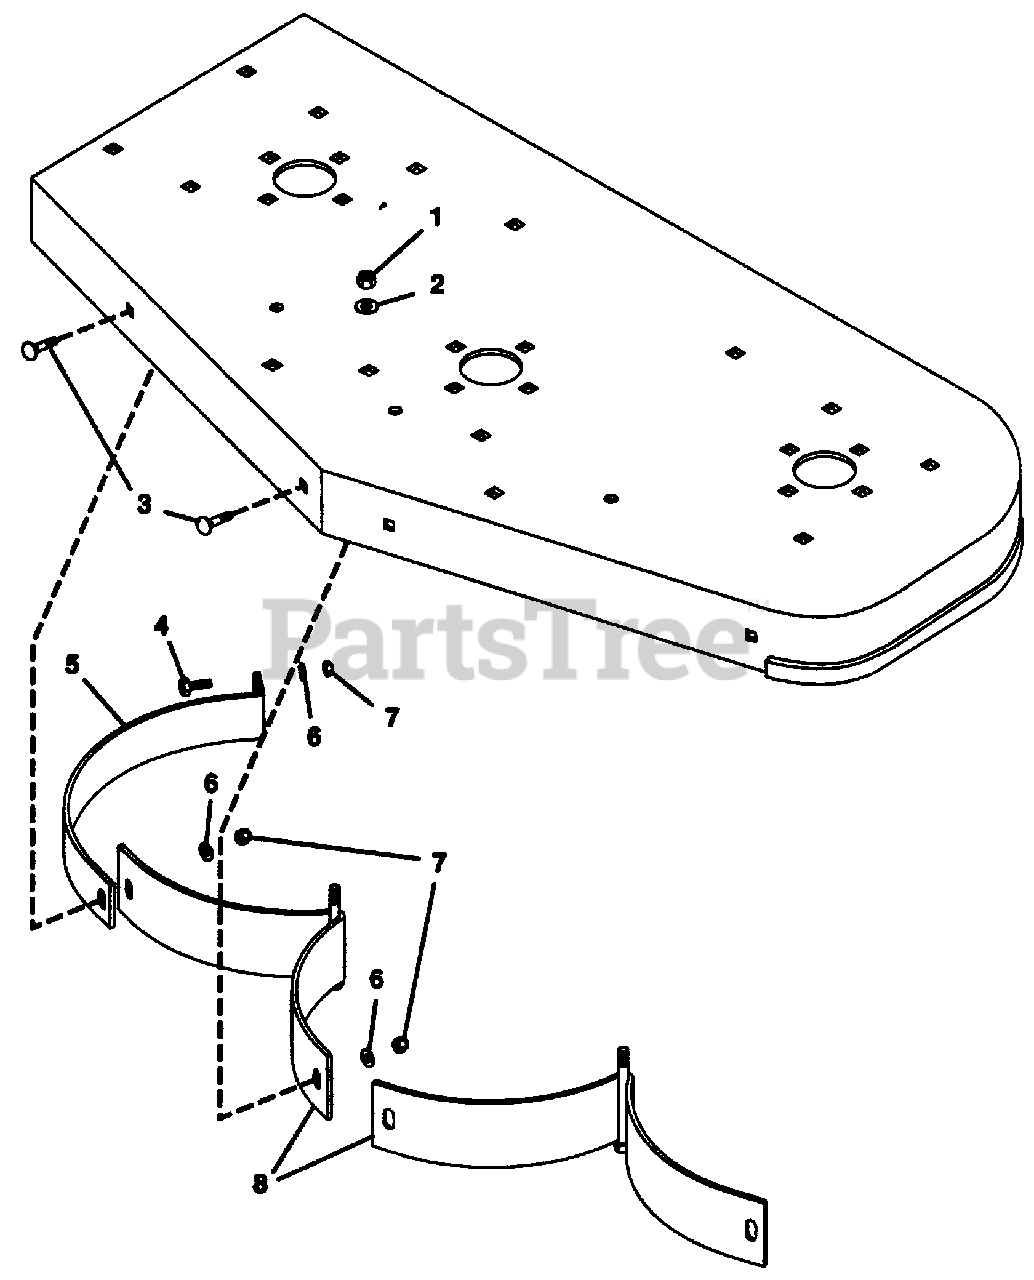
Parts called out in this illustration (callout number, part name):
1	Nut, Lock 3/8-16
2	Washer, Flat .406x.812x.065
3	Bolt, 5/16-18x.875 Rd Hd Sq Nk
4	Bolt, Hex 5/16-18x.75
5	Baffle, Discharge Chute
6	Washer, Flat .344x.688x.065
7	Nut, Lock 5/16-18
8	Weldment, Mulching Baffle
